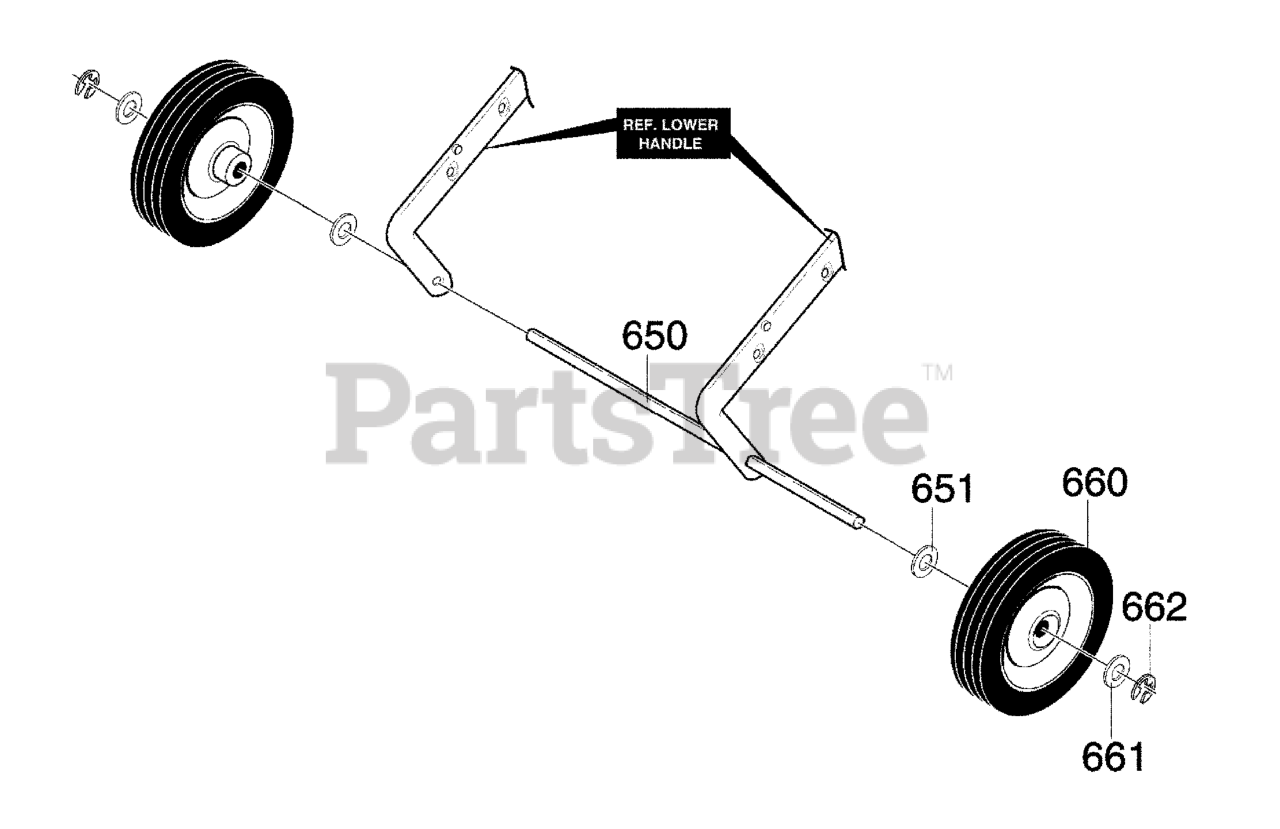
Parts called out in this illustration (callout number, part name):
650	AXLE SHAFT
651	WASHER, FLAT .391X1.00X1.25
660	TIRE & RIM
661	WASHER, FLAT .391X1.00X.125
662	RING, RET E
